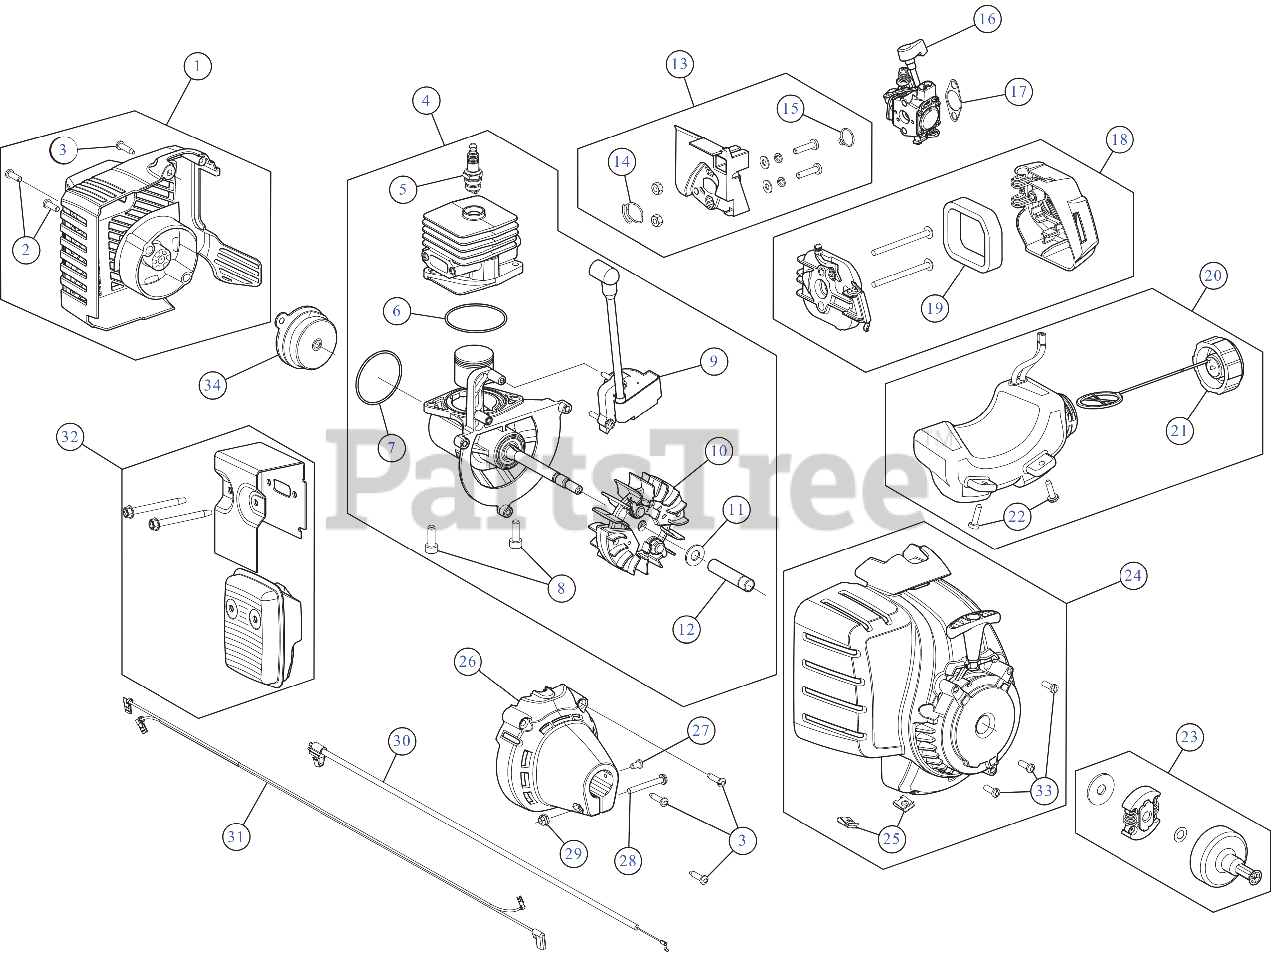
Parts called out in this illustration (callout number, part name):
1	REAR ENG CVR
3	SCREW, #8-16X.750 PH
4	SHORT BLOCK
5	SPARK PLUG
8	SCREW, 1/4-20 x .75
9	MODULE 27CC DIG
10	FLYWHEEL ASSEMBLY
11	BELL WASHER
13	INTAKE ASSEMBLY
16	CARBURETOR
17	GASKET CARB
18	AIRCLEANER COVER ASSEMBLY
19	AIR FLITER
20	FUEL TANK ASSEMBLY
21	FUEL CAP ASSEMBLY
22	SCREW:10-6 x .75
23	SMALL CLUTCH ASSEMBLY W/SMALL DRUM
24	STARTER HOUSING RED
25	NUT, TINNERMAN U-T
26	CLUTCH COVER
27	SCREW, 8-32 x .312 P
28	SCREW
30	THROTTLE CABLE
31	LEAD WIRES
32	MUFFLER ASSEMBLY
33	SCREW:10-32X.562:#8P
34	ELECTRIC START COVER
